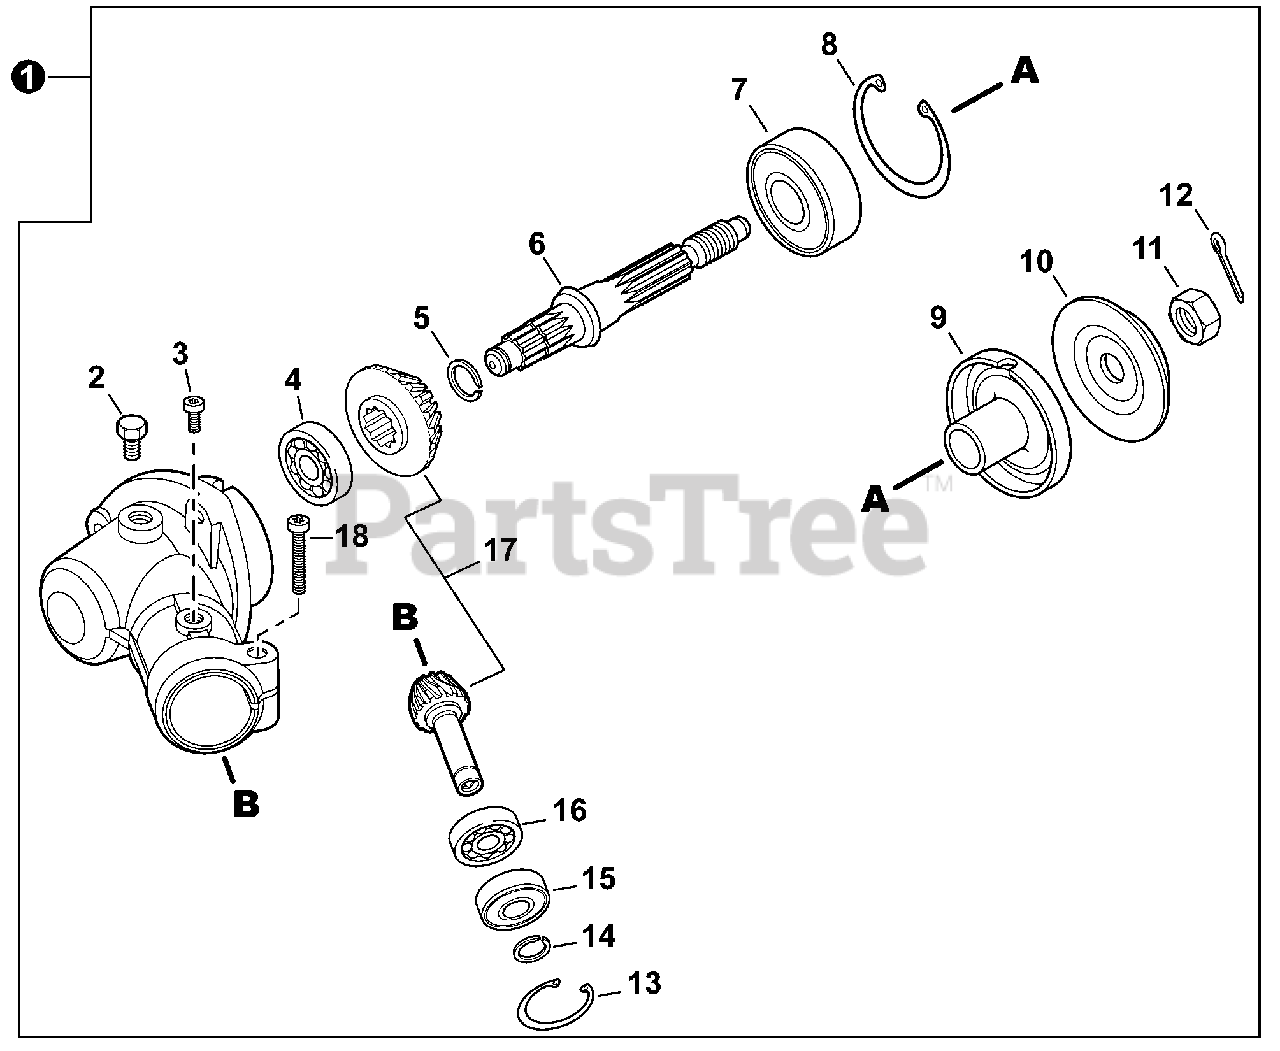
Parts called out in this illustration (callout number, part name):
1	GEAR CASE ASSY
2	BOLT M8×8
3	BOLT, TORX 5×12
4	BEARING, BALL 629
5	RING, SNAP Ø12
6	SHAFT, GEAR
7	BEARING, BALL 6302
8	RING, SNAP Ø42
9	PLATE, ADAPTOR - UPPER
10	PLATE, ADAPTOR - LOWER
11	NUT 10×1.25 LH
12	PIN, COTTER 2×22
13	RING, SNAP Ø22
14	RING, SNAP Ø10
15	BEARING, BALL 6900Z
16	BEARING, BALL 6900
17	GEAR SET
18	BOLT, TORX 5×25
